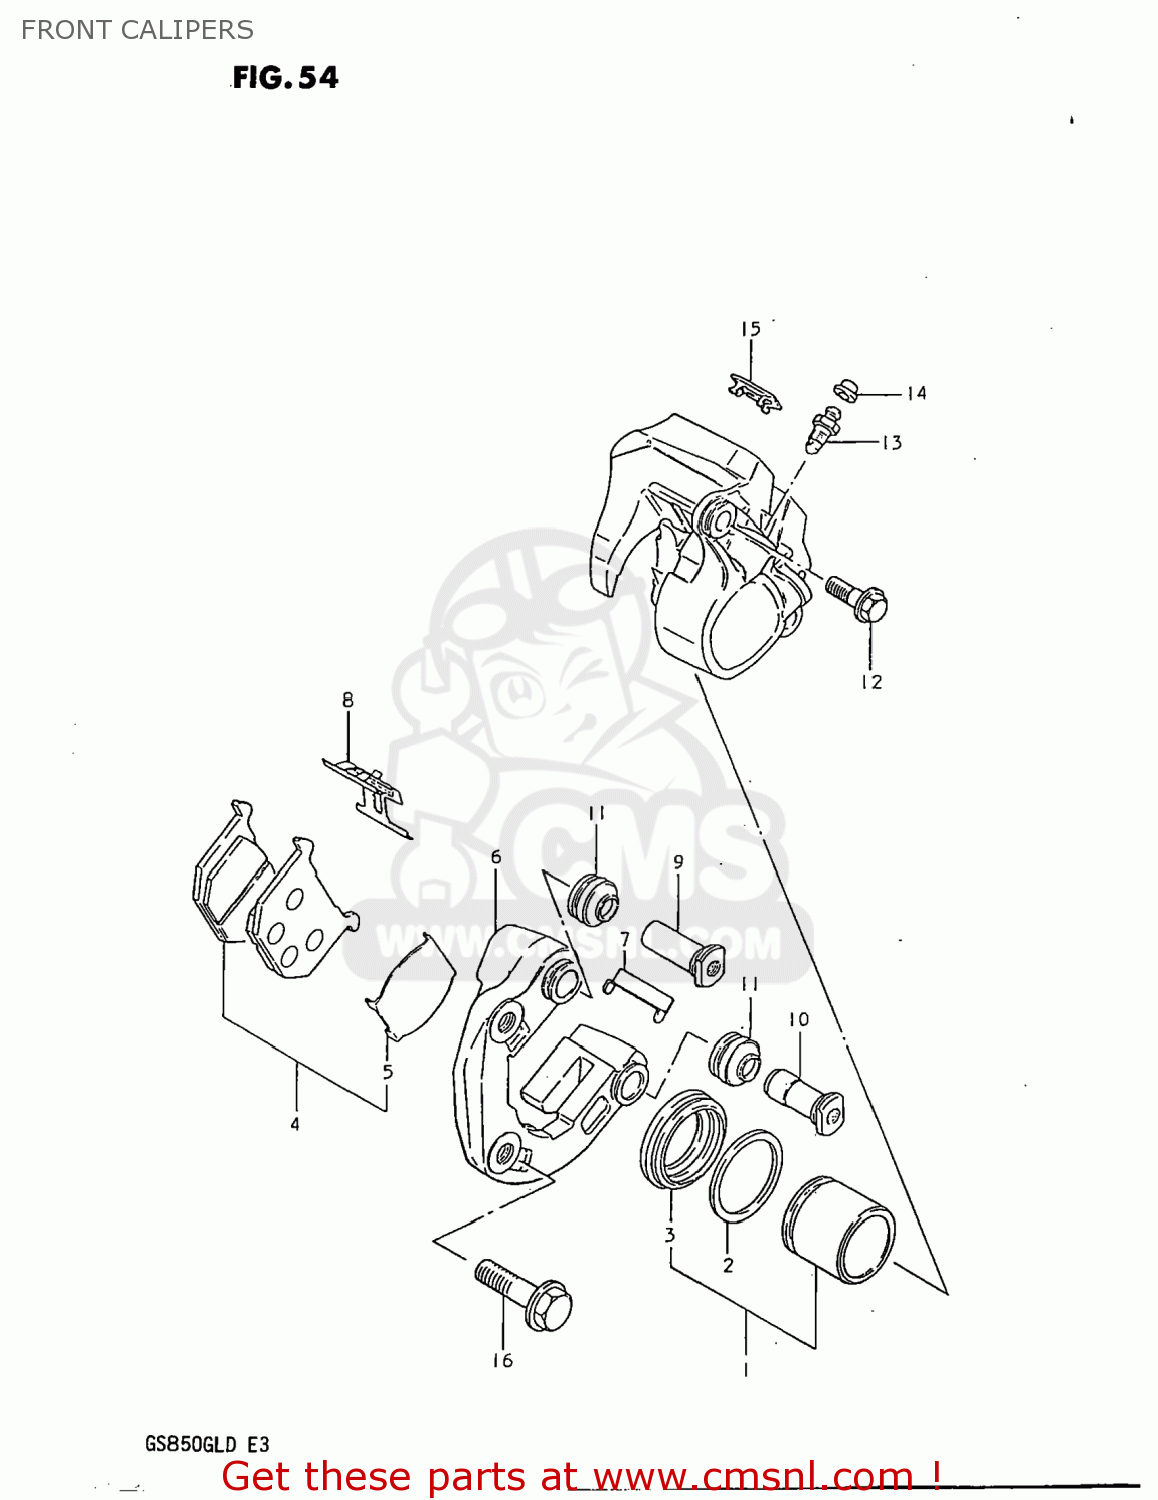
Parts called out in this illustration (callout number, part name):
1	PISTON SET
2	SEAL,PISTON
3	BOOT,PISTON
4	PAD SET,BRAKE (MCA)
5	SHIM,PAD
6	CARRIER,CALIPER
7	GUIDE,PAD
8	SPRING,PAD
9	AXLE NO.1
10	AXLE NO.2
11	BOOT,AXLE
12	BOLT
13	BLEEDER
14	CAP,BREATHER
15	COVER
16	BOLT
